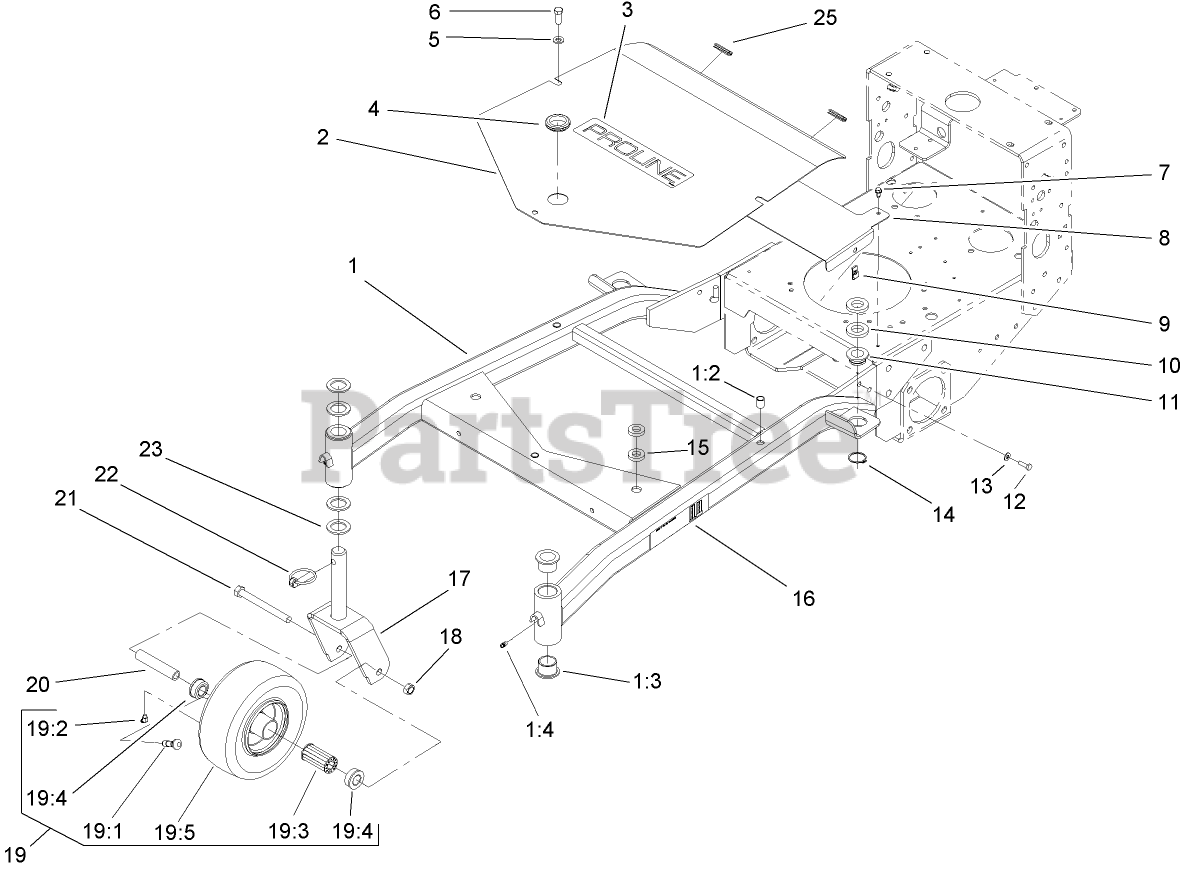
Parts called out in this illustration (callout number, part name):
1	Carrier Frame ASM
1:2	INSERT-NUT
1:3	BUSHING
1:4	FITTING-GREASE
2	Cover-Frame, Carrier
4	GROMMET-RUBBER
5	WASHER-FLAT
6	SCREW-HH
7	SCREW
8	Shield-Heat
9	NUT-SPEED
10	SPACER-SUPPORT, DECK
11	BUSHING-DECK
12	SCREW-HH
13	WASHER-FLAT
14	RING-RETAINING
15	SPACER
17	FORK-CASTOR
18	NUT-HEX
19	CASTER WHEEL ASM
19:1	STEM-VALVE
19:2	FITTING-LUBE, 45 DEG
19:3	BEARING
19:4	BEARING-OUTSIDE
19:5	TIRE-TUBELESS
20	BUSHING-SPANNER
21	SCREW-HH
22	PIN-LYNCH
23	WASHER-THRUST
25	SEAL-STRIP, 1.5 IN
